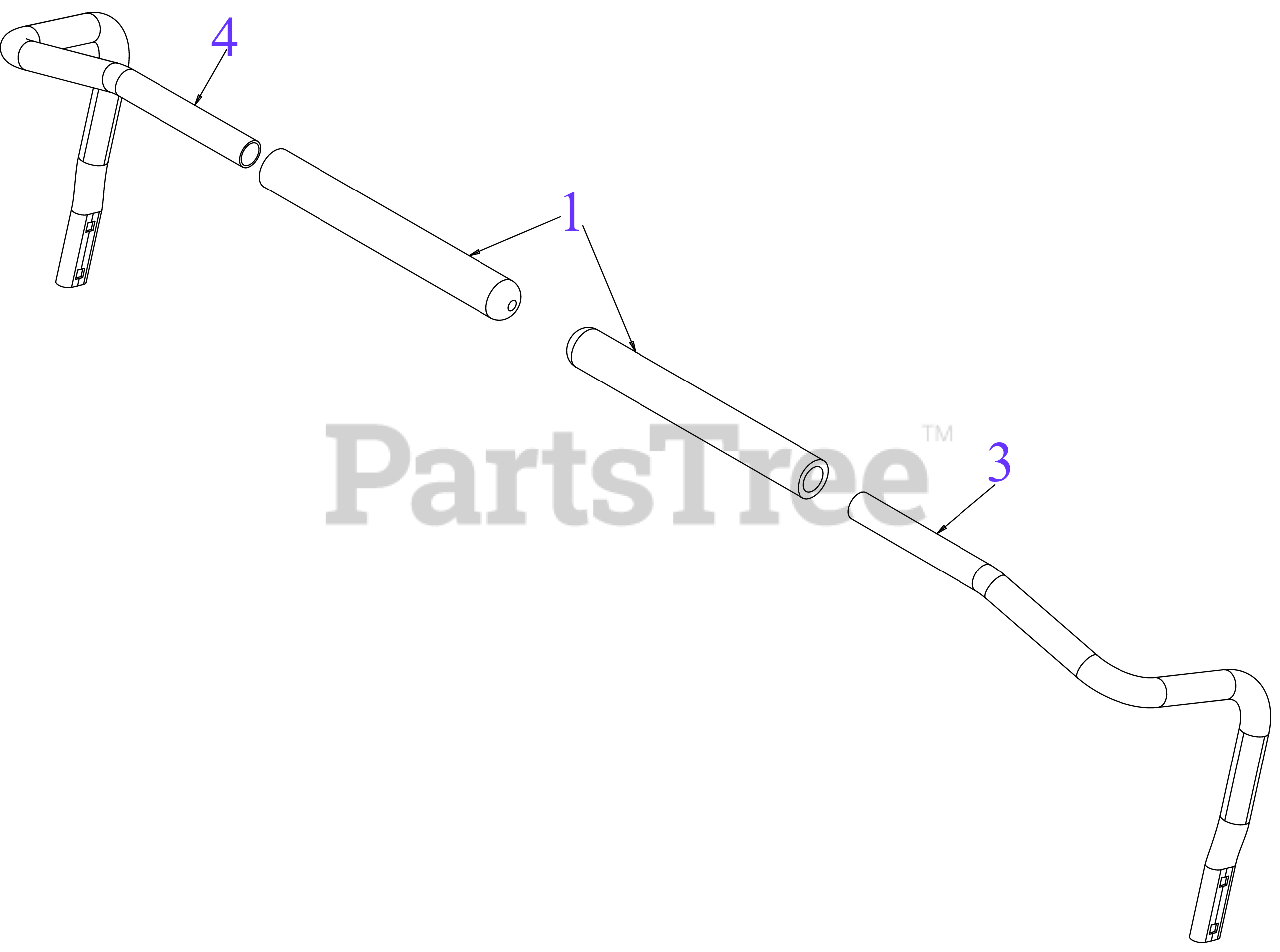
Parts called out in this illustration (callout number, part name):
1	LAPBAR GRIP 1.430OD x 10.62
3	LAPBAR (RH)
4	LAPBAR (LH)
